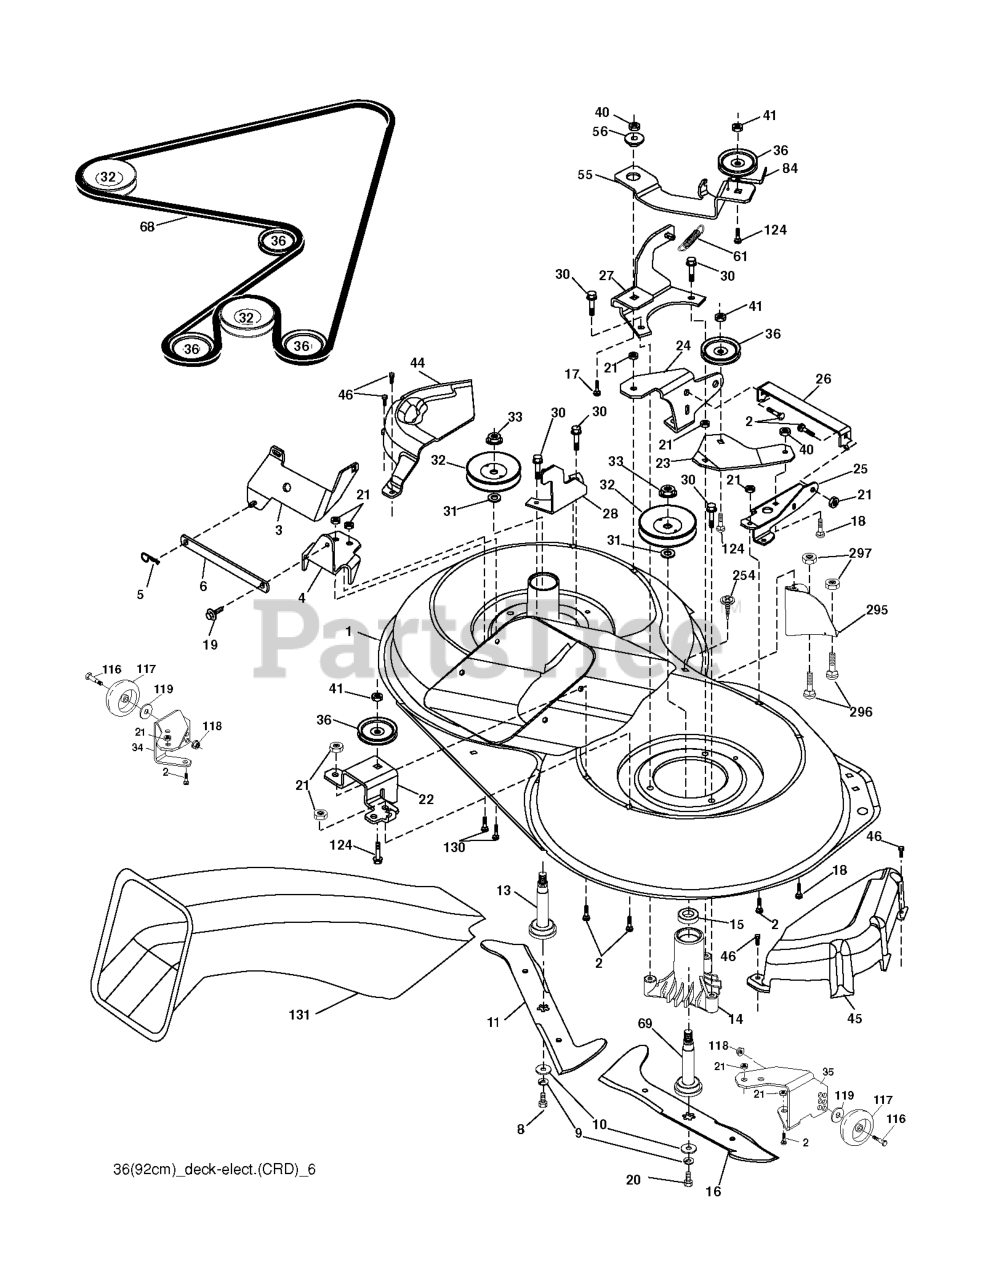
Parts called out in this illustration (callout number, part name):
2	RP BOLT 5/16-18 X3/4 ZN/YEL GR
5	RETAINER-SPRNG RB
6	BAR.SWAY.92.CRD
8	BOLT.3/8-24X1.25 GR8
9	LOCKWASHER
10	WASHER.BLADE
13	SHAFT ASM VENT
14	HOUSING.MANDREL.VENTED (MACHD)
17	BOLT.3/8-14X1.25
19	BOLT SHD 5/16-18
20	BOLT.3/8-24X1.25GR8. LHTHRD
21	LOCKNUT
26	SUPPORT
30	SCREW, WASHER HEAD
31	WASHER.SPACER.MANDREL
32	PULLEY MANDREL
33	NUT.FLANGE.LOCK.TOP
36	PULLEY.IDLER.4.25
41	NUT LOCK FLG 3/8-16 UNC
45	COVER.MANDREL.RH.CRD
46	SCREW.1/4-20X5/8
55	ARM.IDLER.92 CRD.2006
56	SPACER.RETAINER.MOWER
61	SPRING
68	BELT.DRIVE.92CM.CRD.2006
69	SHAFT.ASM.W/LWR.BRG.RH.THREAD
84	KEEPER, BELT IDLER
116	BOLT.SHOULDER.3/8-16X3-5/8.
117	RP WHEEL. GUAGE RALLY
118	NUT LOCK FLG 3/8-16 UNC
119	WASHER
124	BOLT.3/8-16X1.50
130	BOLT.CARR.SQNK.5/16-18UNC.X3/4
131	CHUTE BAGGER
254	SCREW 3/8-16X1
296	BOLT
297	NUT CENTERLOCK
